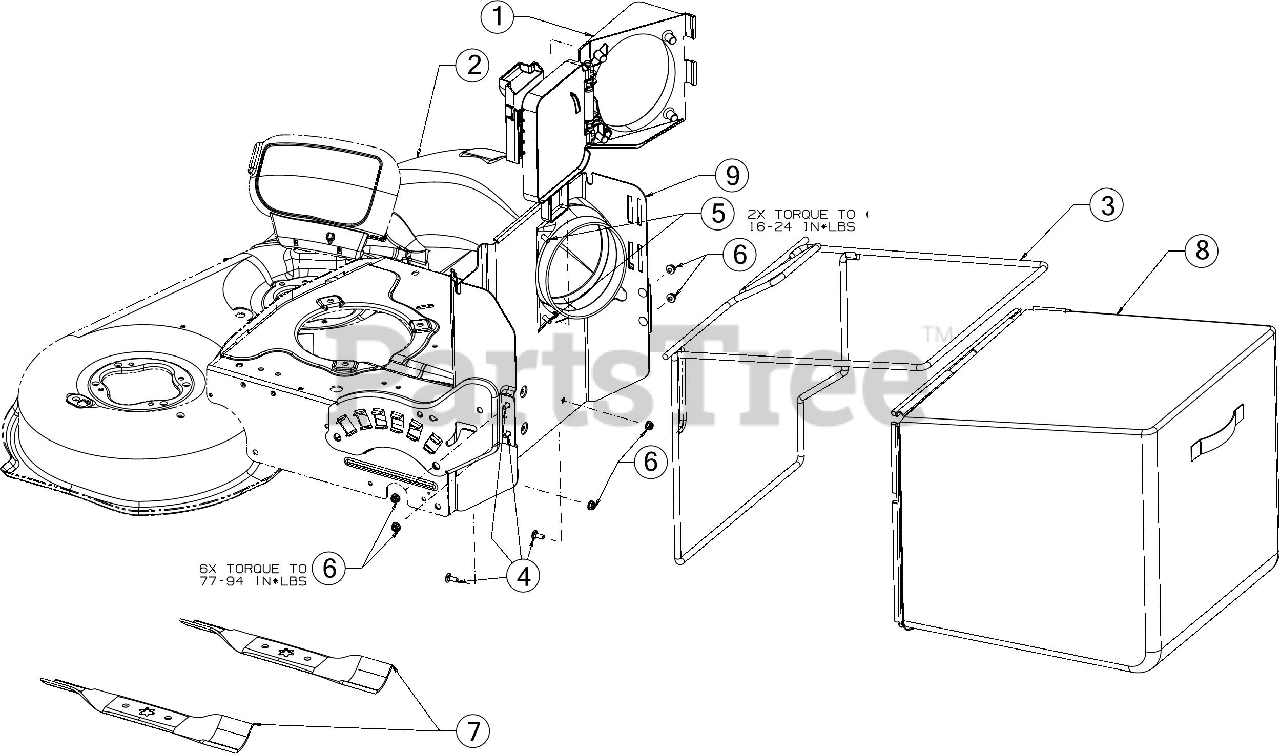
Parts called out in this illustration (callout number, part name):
1	GRASSBAG DOOR ASSEMBLY
2	CHUTE ASSEMBLY
3	GRASSBAG FRAME
4	CARRIAGE BOLT 1/4-20 x .62
5	SCREW 1/4 x .750
6	FLANGE LOCK NUT
7	BLADE (HI LIFT) (14.2)
8	GRASSBAG - PLAIN 28" MOWER
